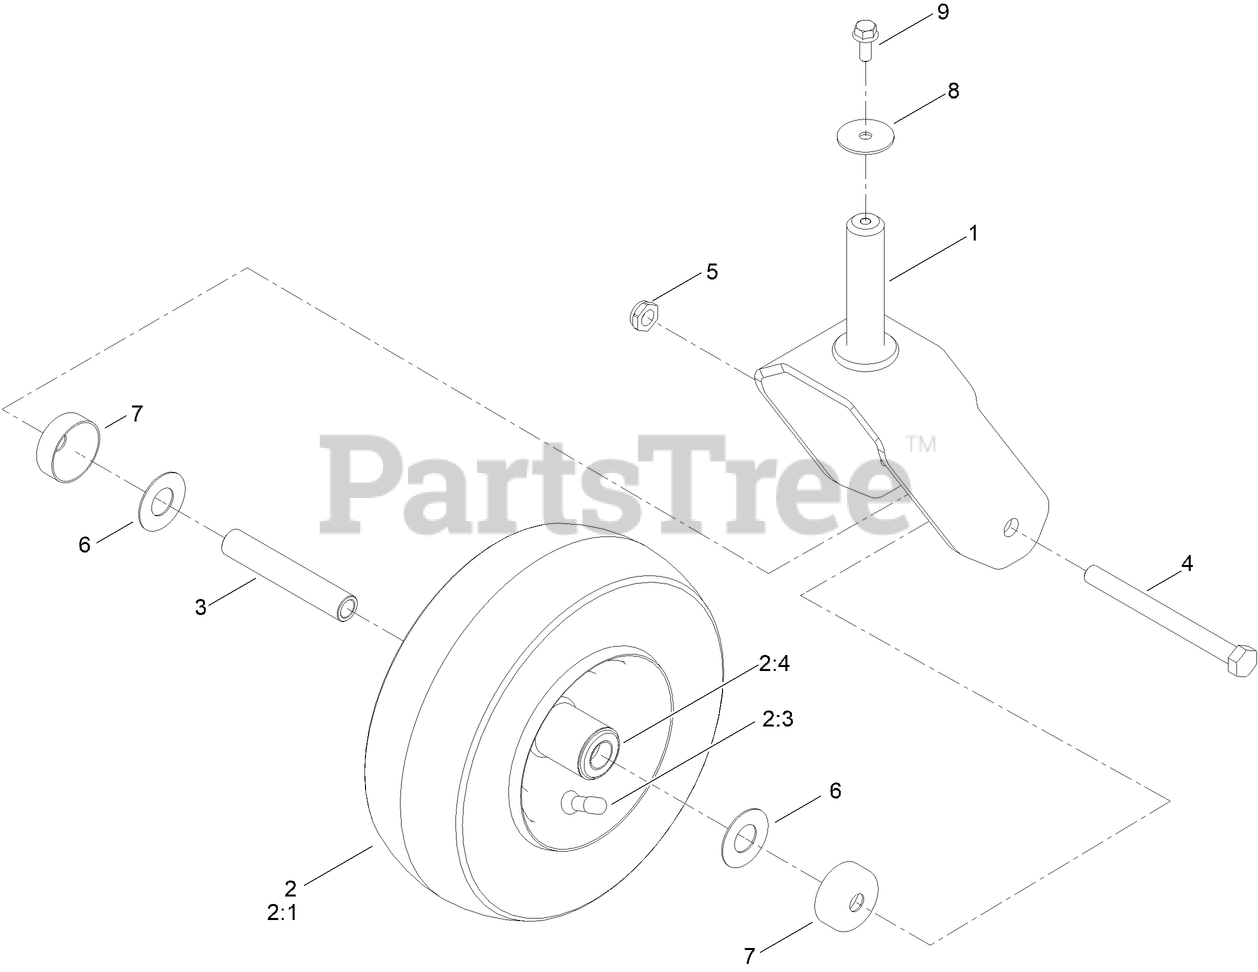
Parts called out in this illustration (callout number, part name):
1	FORK ASM
2	TIRE ASM
2:4	BEARING
3	SPACER-SPANNER
4	SCREW-HH
5	NUT-LOCK, NI
6	WASHER
7	GUARD-SEAL
8	WASHER-FLAT
9	SCREW-HHF
